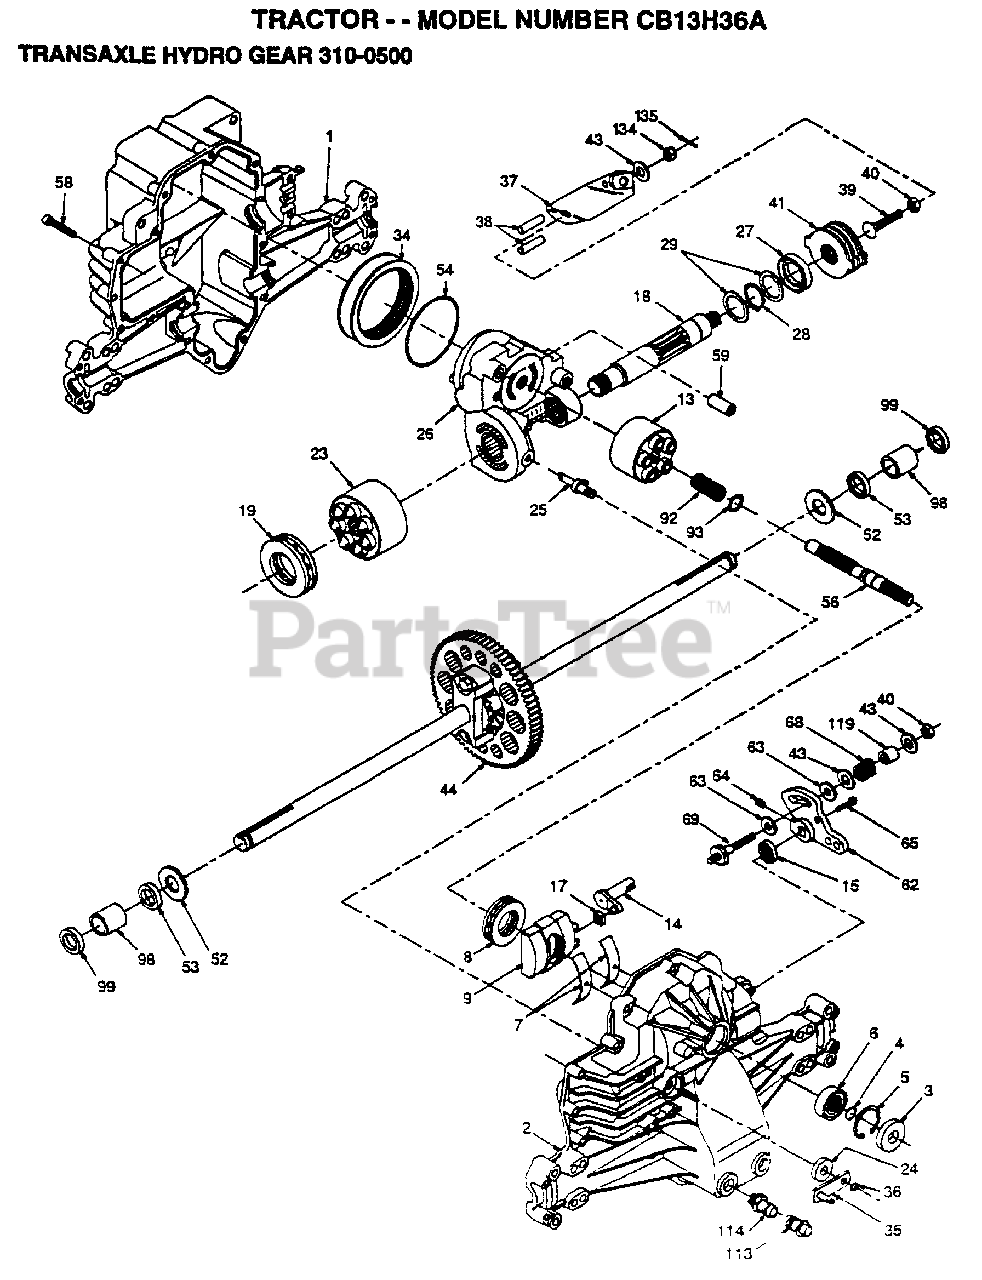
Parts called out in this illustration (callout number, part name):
1	HOUSING.L.44863RM
2	HOUSING.UPR.70122
3	SEAL.9008000-0128
4	RING.RET.2003016.
5	RING.RET.2003052.
6	BEARING.(50552)42X68X16
7	CRADLE- 2003023.
8	BEARING.2003044.
9	SWASHPLT.2003087.
13	BLOCK.CLYN.70079.
14	ARM.TRUN.2003005.
15	SEAL.9008000-0126
17	GUIDE.2000015.
18	SHAFT.HYD.2003557
19	BEARING.THS.50019
23	BLOCK.CYLIN.70082
24	SEAL.LIP.45074
25	ACTUATOR.2003555
26	KIT.CENTER.70133
27	SEAL.LIP.45075
28	RING RETAIN 50007
29	WASHER.44872
34	ELEMENT.OIL.44964
35	ARM.BYPASS.50270
36	RING.RETAIN.44870
37	ARM.ACTUAT.23710
38	PIN.ACTUAT.44891
40	NUT.LOCK.HX.50108
41	KIT.BRAKE.70135
43	WASHER HYD 44130
44	DIFFERNTIAL.70126
52	WASHER.HYD.44875
53	SEAL.HYDRO.45076
54	O RING.HYD.45077
56	SHAFT.INPUT.50005
58	BOLT.1/4-20.44876
59	PIN.HYDRO.50002
62	ARM.CONTROL.50254
63	PUCK.DAMPER.50281
64	SCREW.SET.50018.
65	BOLT #8-32 X .875
68	SPRING.HYD.50277
69	STUD.5/16-24.DANA
92	SPRING.2003014.
93	WASHER.2003017
98	BEARING.SLV.50137
99	SEAL.WIPER.50941
113	CAP.VENT.70109
114	O-RING.ASM.70110
119	SPACER.HYD.50278
134	NUT.CAS.HYD.44142
135	PIN.COT.HYD.44101
